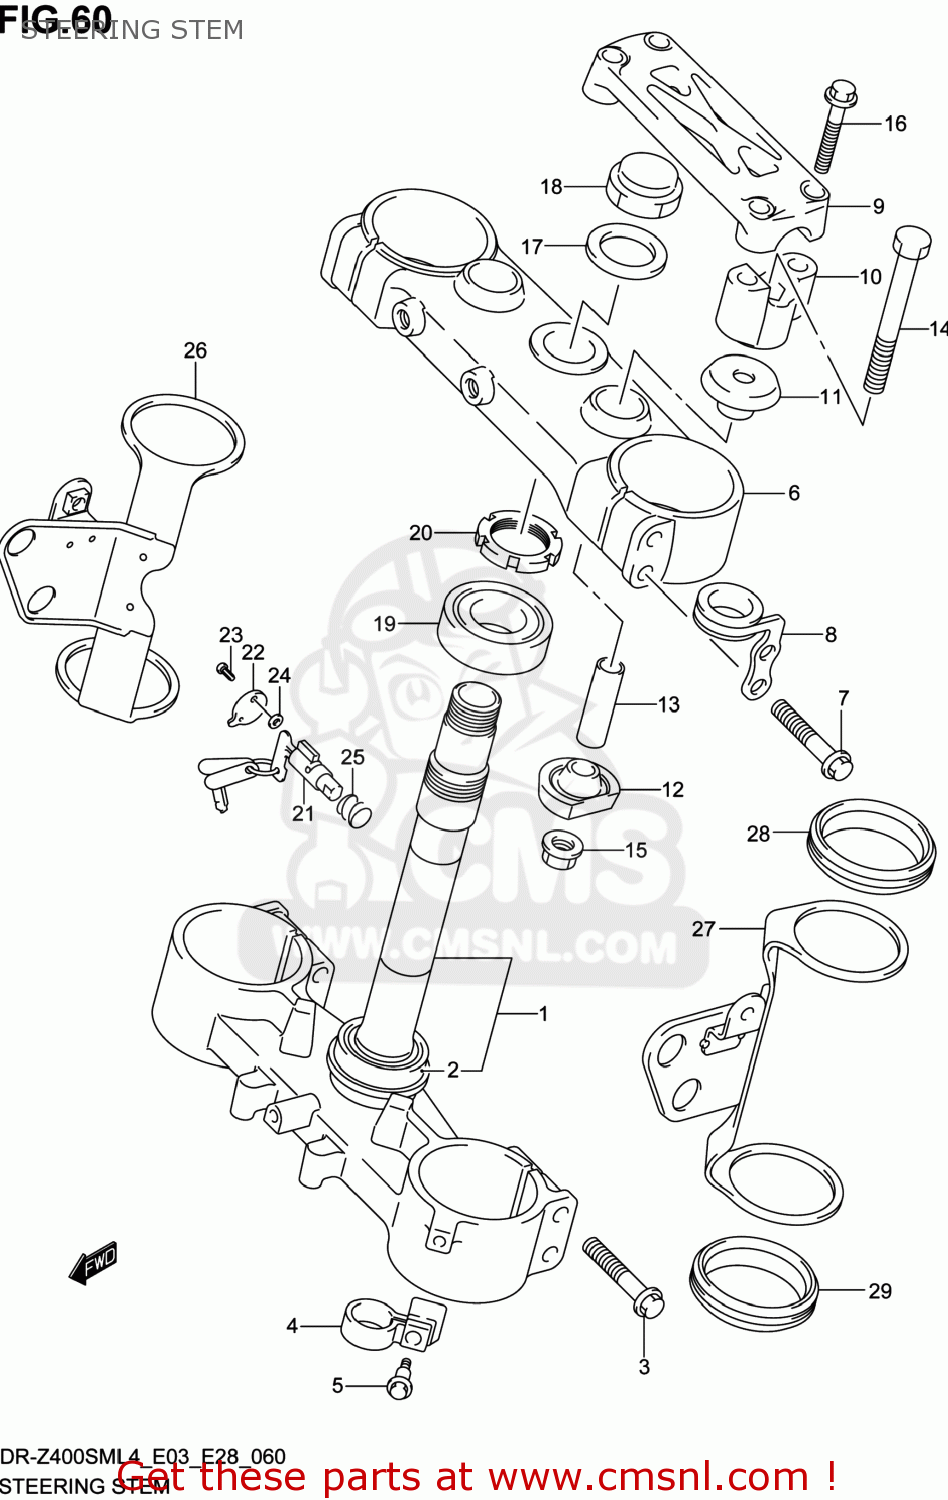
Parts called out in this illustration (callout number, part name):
1	BRACKET,UNDER
2	BEARING(30X52X16)
3	BOLT
4	GUIDE,FR BRAKE HOSE
5	BOLT(6X20.5)
6	BRACKET,UPR
7	BOLT
8	GUIDE,CABLE
9	HOLDER,HANDLEBAR UPR
10	HOLDER,HANDLE LWR
11	CUSHION,RUBBER
12	CUSHION,RUBBER UNDER
13	SPACER
14	BOLT
15	NUT
16	BOLT
17	WASHER,STEM HEAD
18	NUT
19	BEARING(30X52X16)
20	NUT,STEERING
21	LOCK ASSY,STEERING
22	CAP,STEERING LOCK
23	PIN,STEERING LOCK
24	WASHER,STEERING LOCK
25	SPRING,STEERING LOCK
26	BRACKET,HEADLAMP HOUSING,R
27	BRACKET,HEADLAMP HOUSING,L
28	DAMPER,HEADLAMP BRACKET UPR
29	DAMPER,HEADLAMP BRACKET LWR
